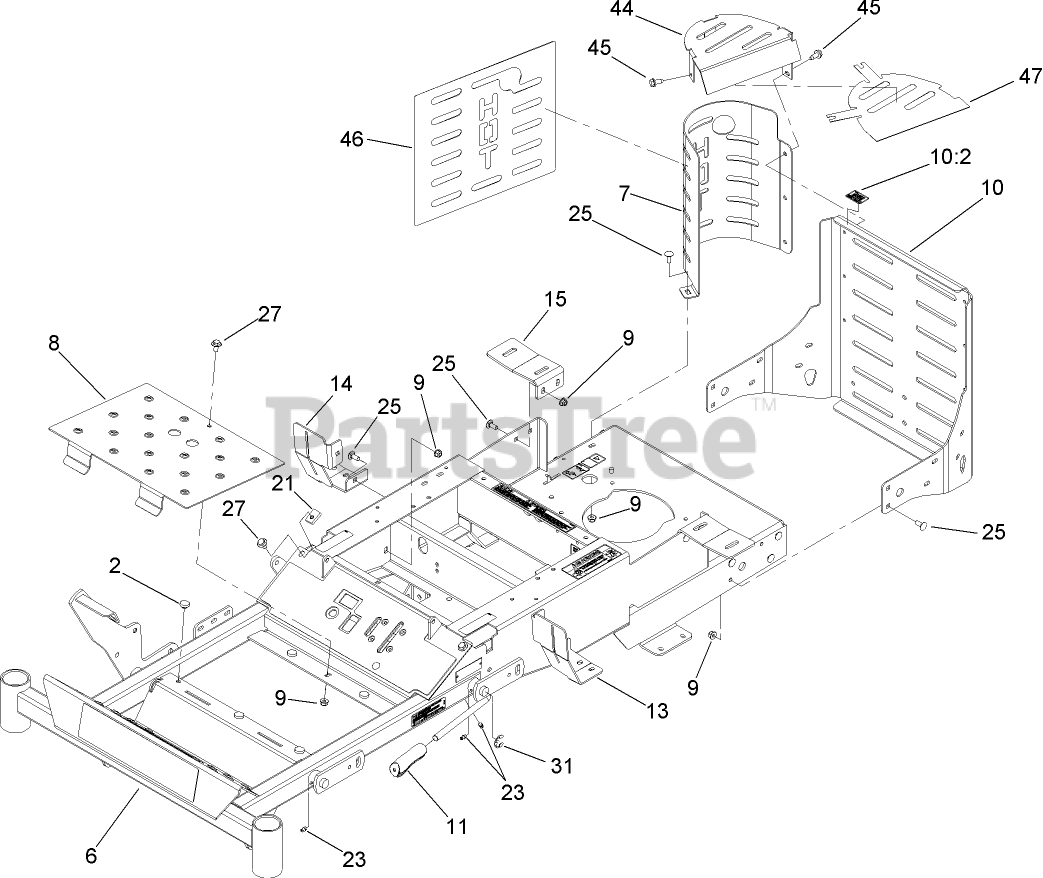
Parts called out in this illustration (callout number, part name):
2	BUMPER
6	DECK ASM
7	GUARD-MUFFLER
8	PLATE-FLOOR
9	NUT-HF, NI
10	REAR GUARD ASM
10:2	DECAL-SURFACE, HOT
11	GRIP-LEVER, BRAKE
13	MOUNT-TANK, FUEL (LH)
14	MOUNT-TANK, FUEL (RH)
15	BRACKET-FUEL TANK, REAR
21	STOP-MOTION
23	FITTING-GREASE
25	SCREW-CARR
27	SCREW-HHF
31	E-RING
44	SHIELD-HEAT
45	SCREW-HWHTF
46	GUARD-FOIL
47	SHIELD-FOIL
